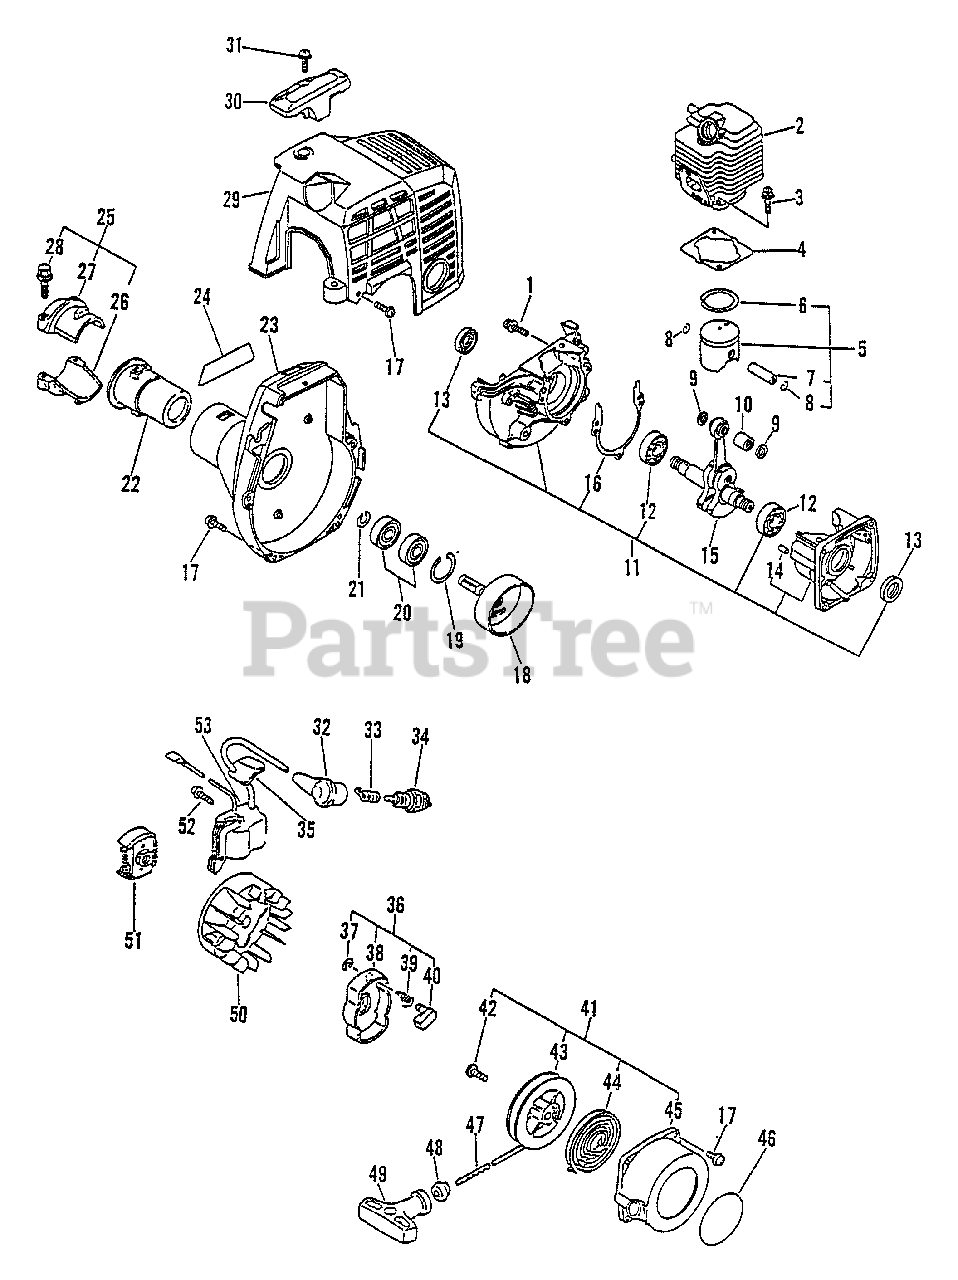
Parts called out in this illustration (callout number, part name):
1	BOLT 5×28
2	CYLINDER
3	BOLT 5×22
4	GASKET, CYLINDER
5	PISTON KIT
6	RING, PISTON
7	PIN, PISTON 8
8	RING, SNAP
9	WASHER, THRUST
10	BEARING, NEEDLE
11	CRANKCASE KIT
12	BEARING, BALL - 6201 C3
13	SEAL, OIL 12
14	PIN, LOCATING 4
15	CRANKSHAFT ASSY
16	GASKET, CRANKCASE
17	BOLT 4×16
18	DRUM, CLUTCH
19	RING, SNAP 28
20	BEARING, BALL 6001
21	RING, RETAINING - 12
23	FAN CASE ASSY
24	LABEL, PE-2400
25	HOLDER KIT
27	HOLDER, MAIN PIPE - UPPER
28	BOLT - 5×25
29	COVER, ENGINE
30	GUARD, TOP
31	SCREW 5×16
32	CAP, SPARK PLUG
33	TERMINAL, SPARK PLUG
34	SPARK PLUG - BPM7A
36	STARTER PAWL ASSY
37	E-RING 4
38	CATCHER, PAWL
39	SPRING, RETURN
40	PAWL, STARTER
41	STARTER ASSY
42	SCREW
43	REEL, ROPE
44	SPRING, RECOIL
45	CASE, RECOIL STARTER
46	LABEL, ECHO
47	ROPE, STARTER
48	GUIDE, ROPE
49	GRIP, STARTER
50	FLYWHEEL
51	CLUTCH ASSY
52	SCREW 4×22
53	COIL, IGNITION
